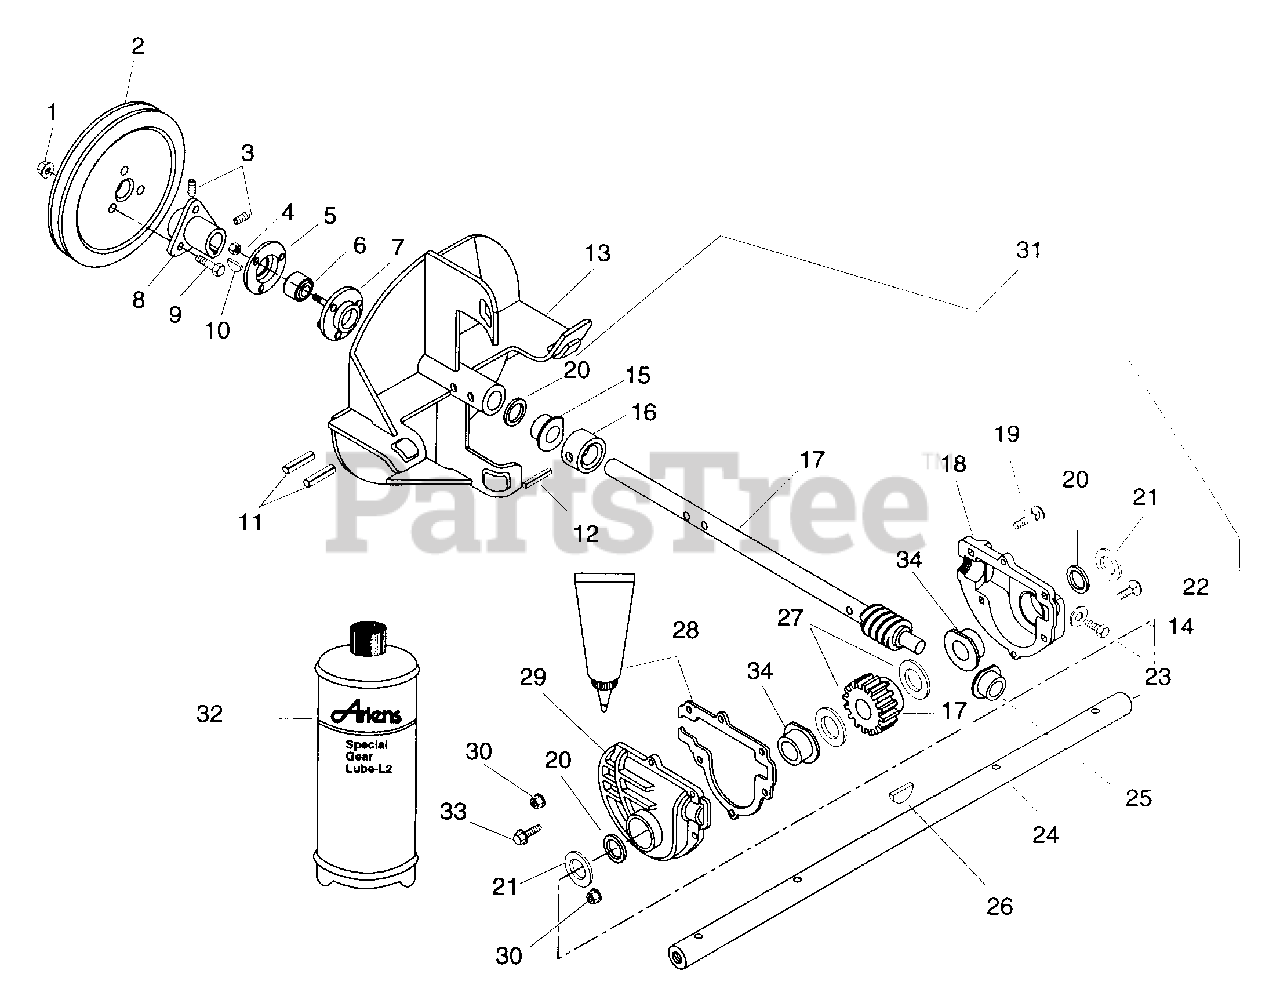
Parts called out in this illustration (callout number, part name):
1	NUT-FLG. .312-18 PL
2	PLY-V 8.50 X 1.25 3BLT
3	SCR-SET .31-18X.38 SKHCUPDL
4	NUT-LK-CTR .250-20 PL
5	BEARING FLANGE
6	BRG-BALL .750X1.750X.50
7	BEARING FLANGE
8	HUB
9	BLT-SERRDHD SL .31-18X.75 YZ
10	KEY-WDRF .188X.875X.375 SAE11
11	PIN-ROLL .250X1.25
12	PIN-GRV .188X1.25 TP A
13	IMPELLER - 10"
14	WSHR-FIBER .437X.656X.032
15	BSHG-FLG .750X1.000X.750X1.250
16	THRUST COLLAR
17	SHAFT AND WORM GEAR ASSEMBLY
18	LS CASE HALF LH SMALL BORE
19	BLT-RDHDSQNK .25-20X1.25 GR5PL
20	SEAL-OIL .750X1.375X.250
21	WSHR-FL-STL.812X1.500X.139
22	BLT-RDHDSQNK .25-20X.88 PL
23	SCR-TAP .375-16X .50 HWH PL TR
24	SHAFT, RAKE - 20"
24	SHAFT, RAKE - 24"
25	BSHG-FLG .500X.750X.750X1.000
26	KEY-WDRF .188X.625X.25 SAE 61
27	WSHR-HDND-THRST .755X1.40X.062
28	LOCTITE 518 GASKET--6ML TUBE
29	LS CASE HALF RH SMALL BORE
30	NUT-LK-FLG .250-20 PL
31	GEAR CASE - 20" - ALUMINUM
31	GEAR CASE - 24" JD - ALUMINUM
32	ARIENS 16 OZ.BOTTLE OF L2 LUBE
33	SCR-TAP 10-24X.75 HWH PL TR
34	BSHG-FLG .75X1.00
